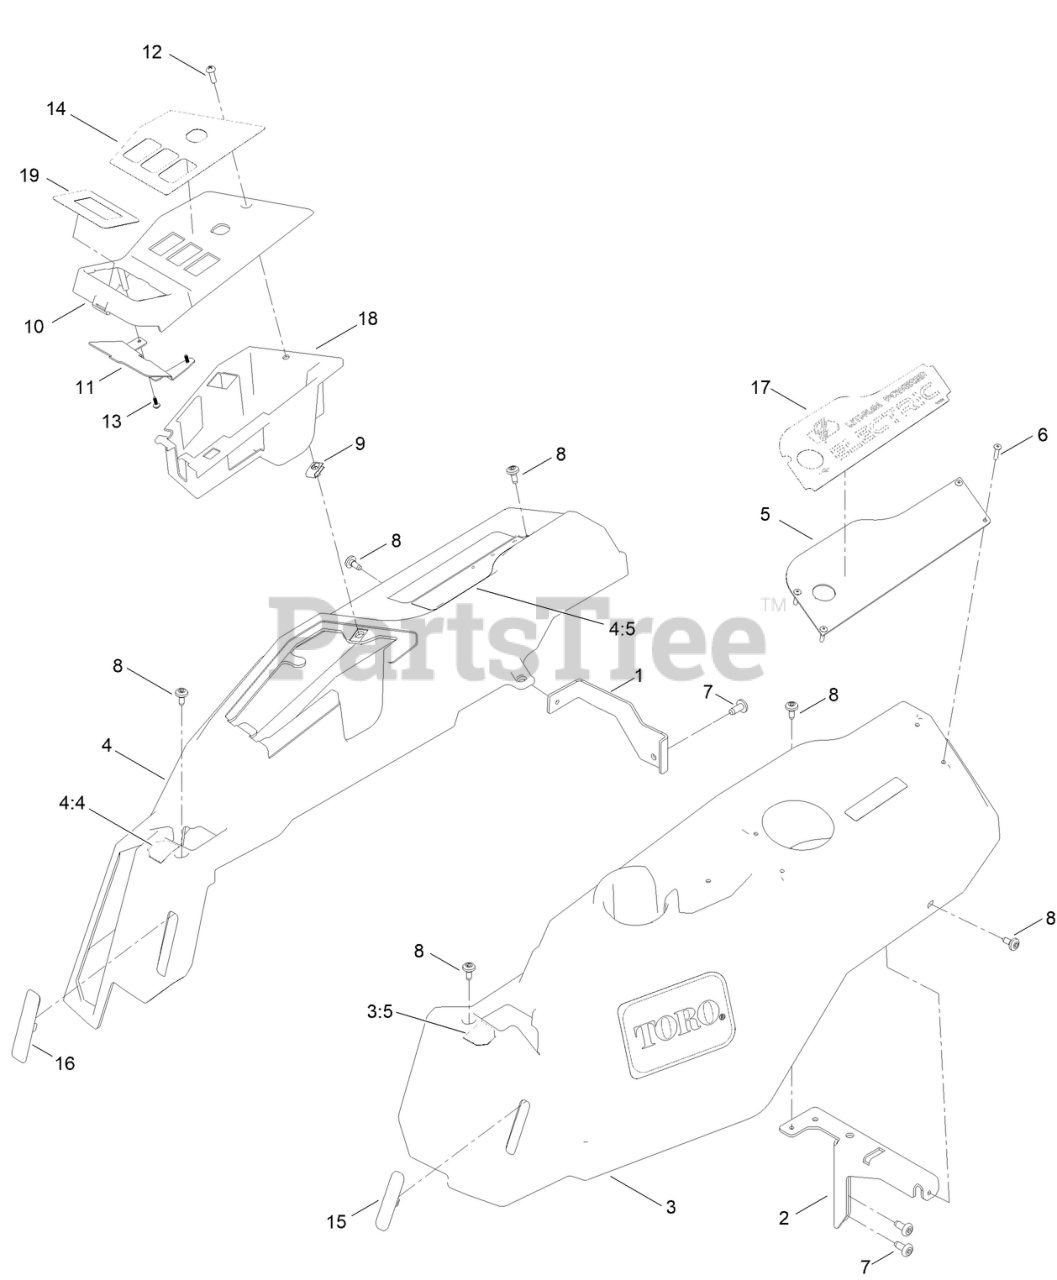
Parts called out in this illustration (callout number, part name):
1	BRACKET-POD
2	SUPPORT-POD, LH
3	POD-LH
3:5	DECAL - CONTROL LEVER, LH
4	POD-RH, MYRIDE
4:4	DECAL - CONTROL LEVER, RH
4:5	DECAL-ADJUSTMENT
5	PLATE-COVER, POD
6	RIVET-TRIFOLD
8	SCREW-SHOULDER
10	POD-CONTROL
11	COVER-CONSOLE
12	SCREW-PRH
13	SCREW-PLASTIC,TBFH
14	DECAL-PANEL, CONTROL
15	PLUG-POD, LH
16	PLUG-SC
17	Decal-60V Lithium
18	COVER-SWITCH
19	DECAL-GT DISPLAY
